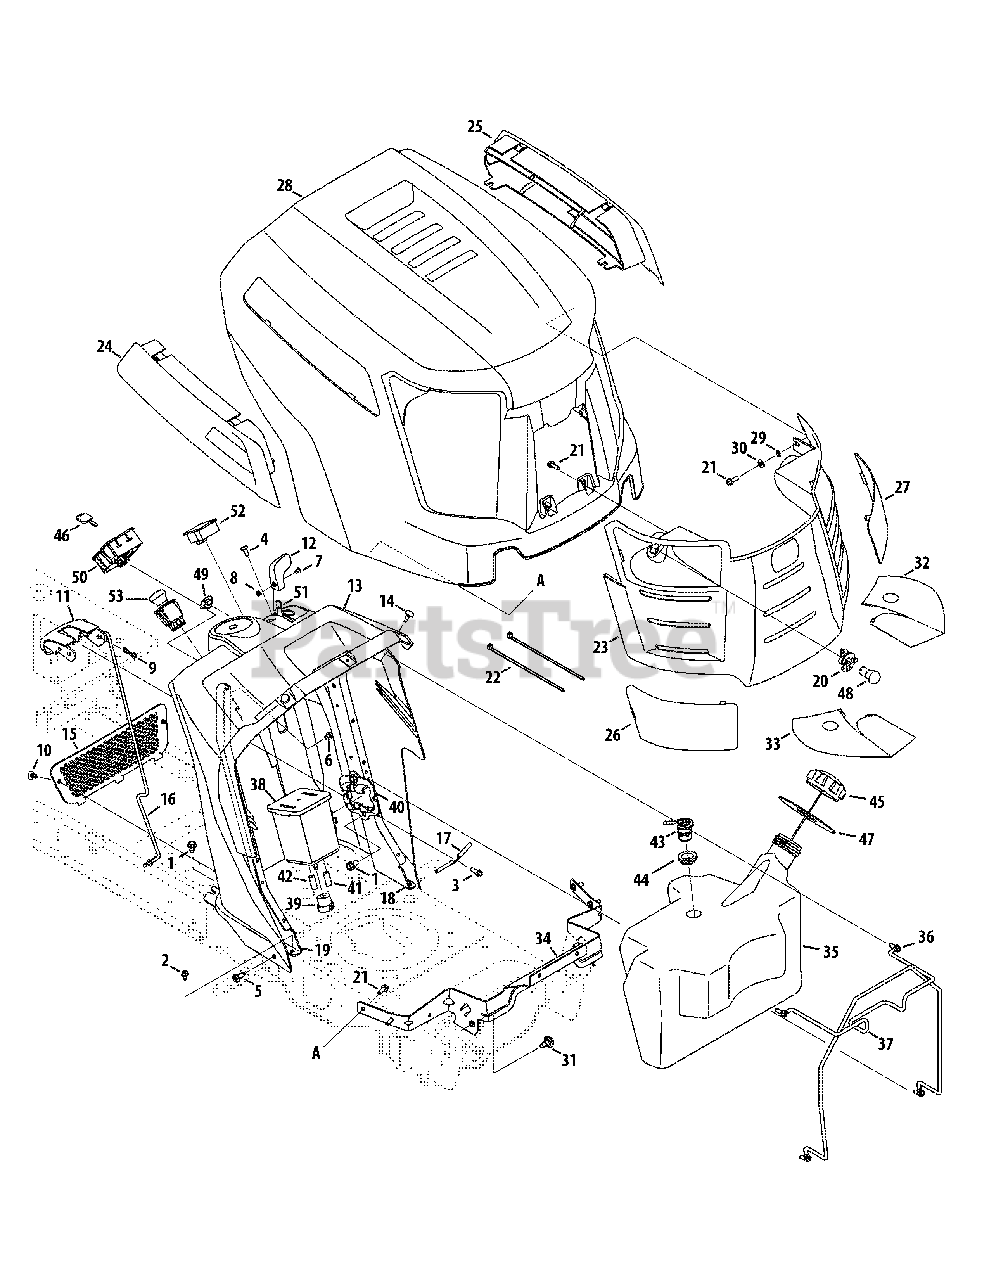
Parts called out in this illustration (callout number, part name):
1	Screw, Self-tapping, 5/16-18, .750
2	Screw, Self-tapping, 1/4-20, 0.500
3	Screw, HL, 1/4-15, 0.750
4	Screw, Ab, 1/4-14, 0.625,
5	Screw, Self-tapping, 5/16-18, 0.750,
6	Screw, Self-tapping, 1/4-20 x .625
7	Screw, Mach, #8-32, 0.375
8	Nut, Hex, #8-32
9	Pin, Cotter, Bow-Tie 72
10	Clip, Ratchet, .250 Dia
11	Lever, Dash, Cruise/Brake
12	Knob, Throttle
13	Dash Panel, A-Style, Man PTO
14	Bumper, .62 Dia X .3
16	Rod, Control, Latch
17	Rod, Lever, Bent
18	Support, Dash, Plate LH
19	Support, Dash, Plate RH
20	Socket, Lamp
21	Screw, 1/4 Dia, .750
22	Tie, Cable, Push Mount 7.5 Lg
23	Grille Ass’y (Incl. 26, 27, 32 & 33)
24	Scoop, Hood, RH A-Style
25	Scoop, Hood, LH A-Style
26	Lens, Hood, RH A-Style
27	Lens, Hood, LH A-Style
28	Hood, A-Style
29	Washer, Lock, 1/4, External
30	Washer, Flat, .271, .630, .065
31	Screw, Shoulder, .43x.29, 5/16-18
32	Reflector, Cub A Style, LH
33	Reflector, Cub A Style, RH
34	Bracket, Pivot, Hood A-Style
35	Tank, Fuel, 3.75 Gal.
35	Tank, Fuel, 3.30 Gal. (CA)
36	Screw, Self-tapping, 1/4-20, .625
36	Screw, Self-tapping, 1/4-20, .75 (CA)
37	Rod, Support, Fuel Tank
38	Canister, Carbon, 5 Gallon (CA)
39	Filter, Vent, Canister (CA)
40	Bracket, Adapter, Canister (CA)
41	Hose, Fuel, Low Perm, 3/16 Wht (CA)
42	Hose, Fuel, Low Perm, 7/32 Yel (CA)
43	Valve, Rollover Grommet (CA)
44	Grommet, Rubber, 23.0 ID (CA)
45	Cap, Fuel
45	Cap, Fuel (CA)
46	Key, Ignition
47	Gasket, Fuel Tank
48	Lamp, 12v
49	Plug, Choke
50	Module Switch, Ignition
51	Cable, Throttle/Choke, 38"
52	Meter, Indicator
53	Switch, Electric PTO, Yellow
